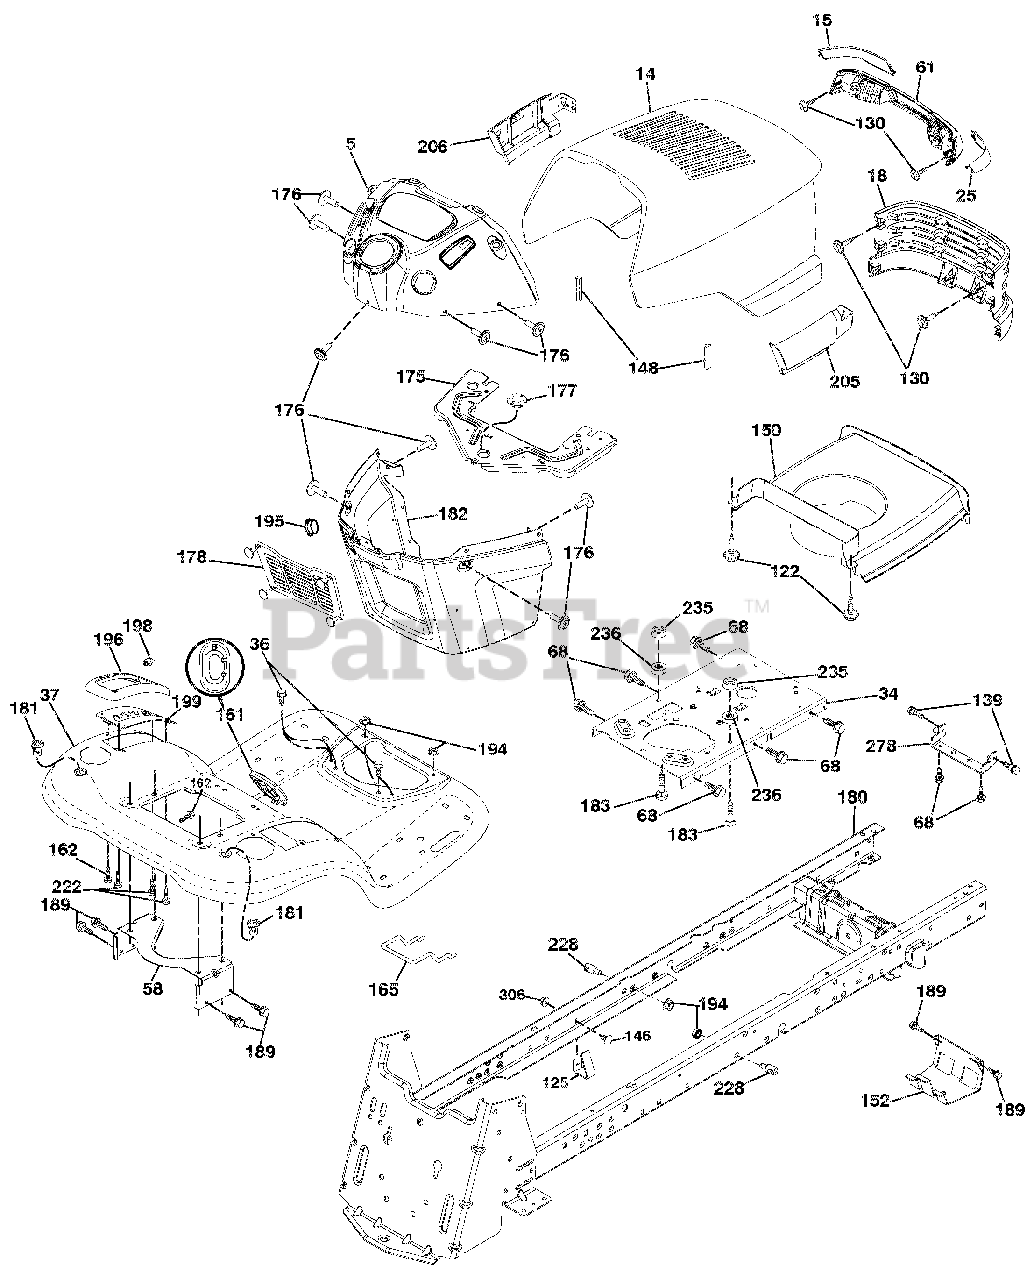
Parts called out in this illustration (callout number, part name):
15	LENS ELITE ARIENS BLACK
18	GRILLE ELITE ARIENS BLACK
25	LENS ELITE HUSQ CLEAR RH
34	PLATE.ENGINE.WELDED.CHASSIS
36	SCREW.5/16-18X3/4.SMGML.TAP/R
58	FENDER SUPPORT BRACKET
61	ASM LIGHT BOX
68	SCREW.THDROL.5/16-18 X 1/2TYTT
122	SCREW TO 32 X 5/8
125	CLIP.FUEL.LINE
139	BOLT SHOULDER 5/16-18
148	BUMPER HOOD LARGE 1.75
150	AIR DUCT ENGINE ELITE SV
152	SHIELD.BROWNING.W/TEX
161	CONSOLE FUEL WINDOW
162	SCREW.HEX.WSH.HI-LO.1/4X1/2UNC
165	SUPPORT.TANK.REAR.W/TEX
175	CROSSMEMBER LT
176	SCREW.#10-24X5/8.RND.QUDRX.GIM
177	BUSHING.STEERING.YT/GT
178	CARGO ASM NET
180	CHASSIS
181	BUSHING MNT FEND CRGO BLK TEX
182	DASH TOWER LT CCS
183	BOLT.FIN.HEX.5/16-18 UNC X1-1/
189	SCREW.5/16-18X3/4.SMGML.TAP/BL
194	Nut, Lock Hex Flange 5/16-18 u
195	PLUG HOLE DASH TOWER
196	CONSOLE ASM. DECK LIFT
198	INDICATOR DECK LIFT
199	PLATE DECK LIFT
205	SKIRT SIDE RH ELITE HUSQ 428
206	SKIRT SIDE LH ELITE 428
222	SCREW.THD.ROLL.1/4-20 X 5/8
228	STUD.FASTNER.W/'D'ANTI-ROTATIO
235	SPACER.FENDER
236	NUT.CENTER LOCK.5/16-18 UNC
278	X-PIECE HOOD
306	Nut, Hex, Flangelock 3/8-16
